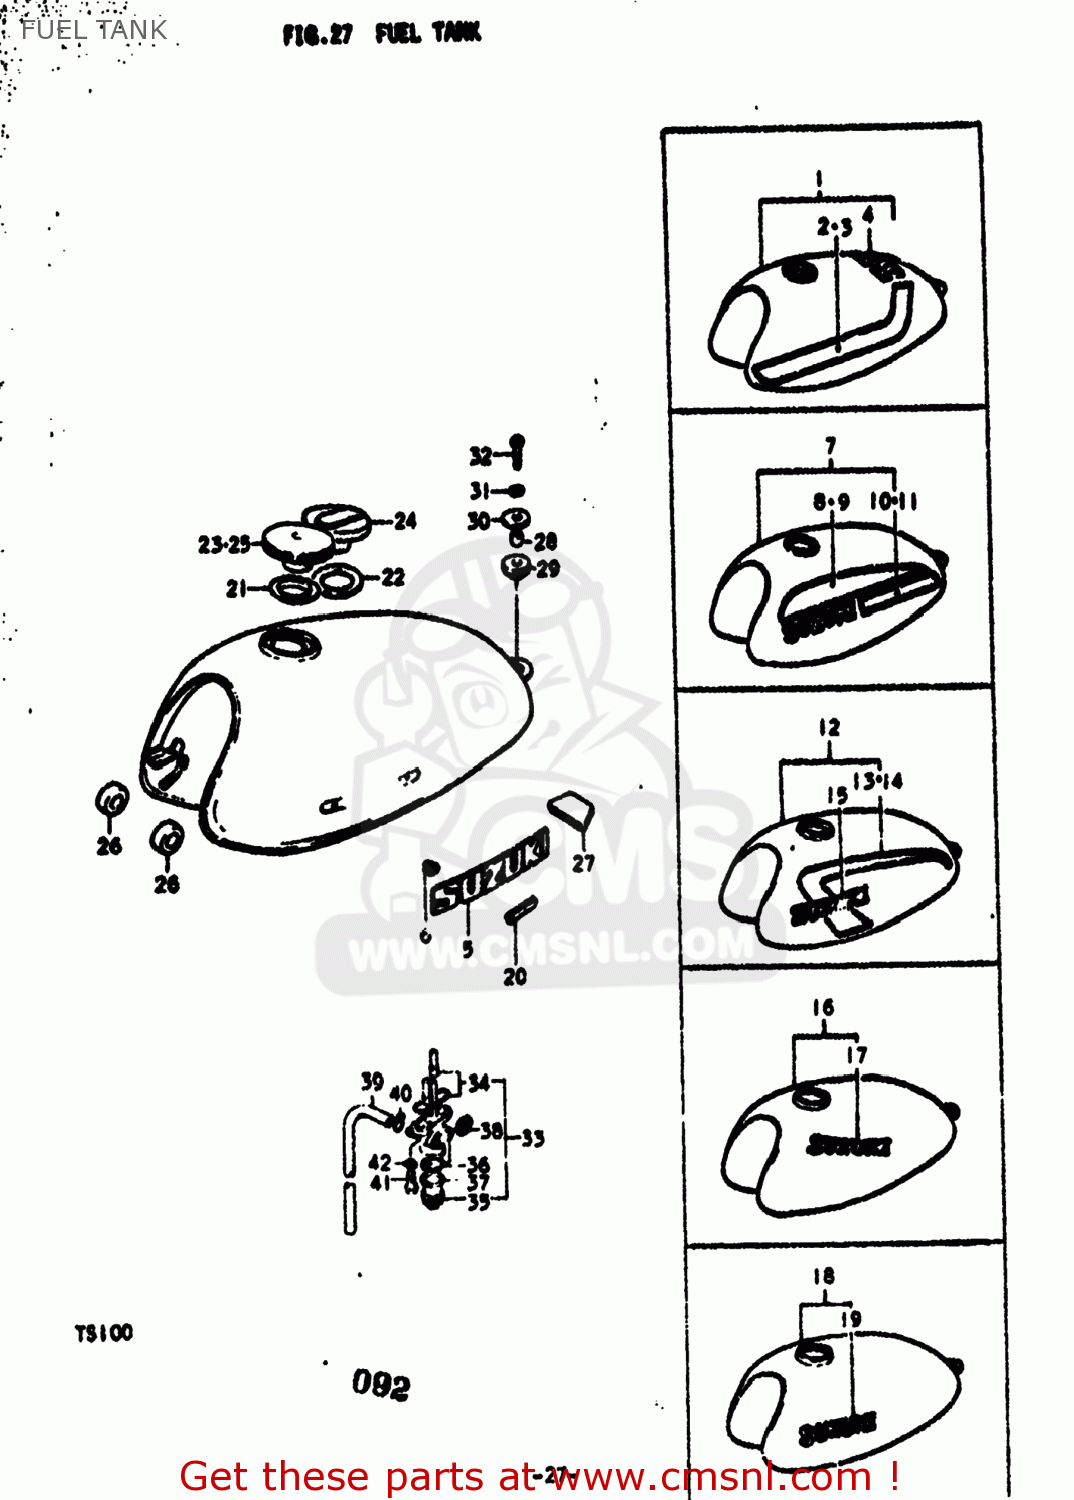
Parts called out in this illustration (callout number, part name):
1	TANK ASSEMBLY,FUEL
2	TAPE,FUEL TANK
3	TAPE,FUEL TANK
5	EMBLEM
6	NUT
7	TANK ASSEMBLY,FUEL
8	TAPE,FUEL TANK
9	TAPE,FUEL TANK
10	EMBLEM
11	EMBLEM,FUEL TANK
12	TANK ASSEMBLY,FUEL
13	TAPE,FUEL TANK
14	TAPE,FUEL TANK
15	EMBLEM
16	TANK ASSEMBLY,FUEL
17	EMBLEM
18	TANK ASSEMBLY,FUEL
19	EMBLEM
21	GASKET,FUEL TANK CAP (NAS)
22	GASKET (NAS)
23	CAP SET,FUEL TANK
24	CAP SET,FUEL TANK
25	CAP,FUEL TANK
26	CUSHION
27	CUSHION
28	SPACER(8.4X12X12)
29	CUSHION
30	WASHER
31	LOCK WASHER
32	BOLT
33	COCK ASSEMBLY,FUEL
34	FILTER SET,FUEL COCK
35	CUP,FUEL COCK STRAINER
36	NET,STRAINER
37	GASKET,FILTER (NAS)
38	GASKET,LEVER (NAS)
39	HOSE
40	CLIP
41	SCREW
42	GASKET
